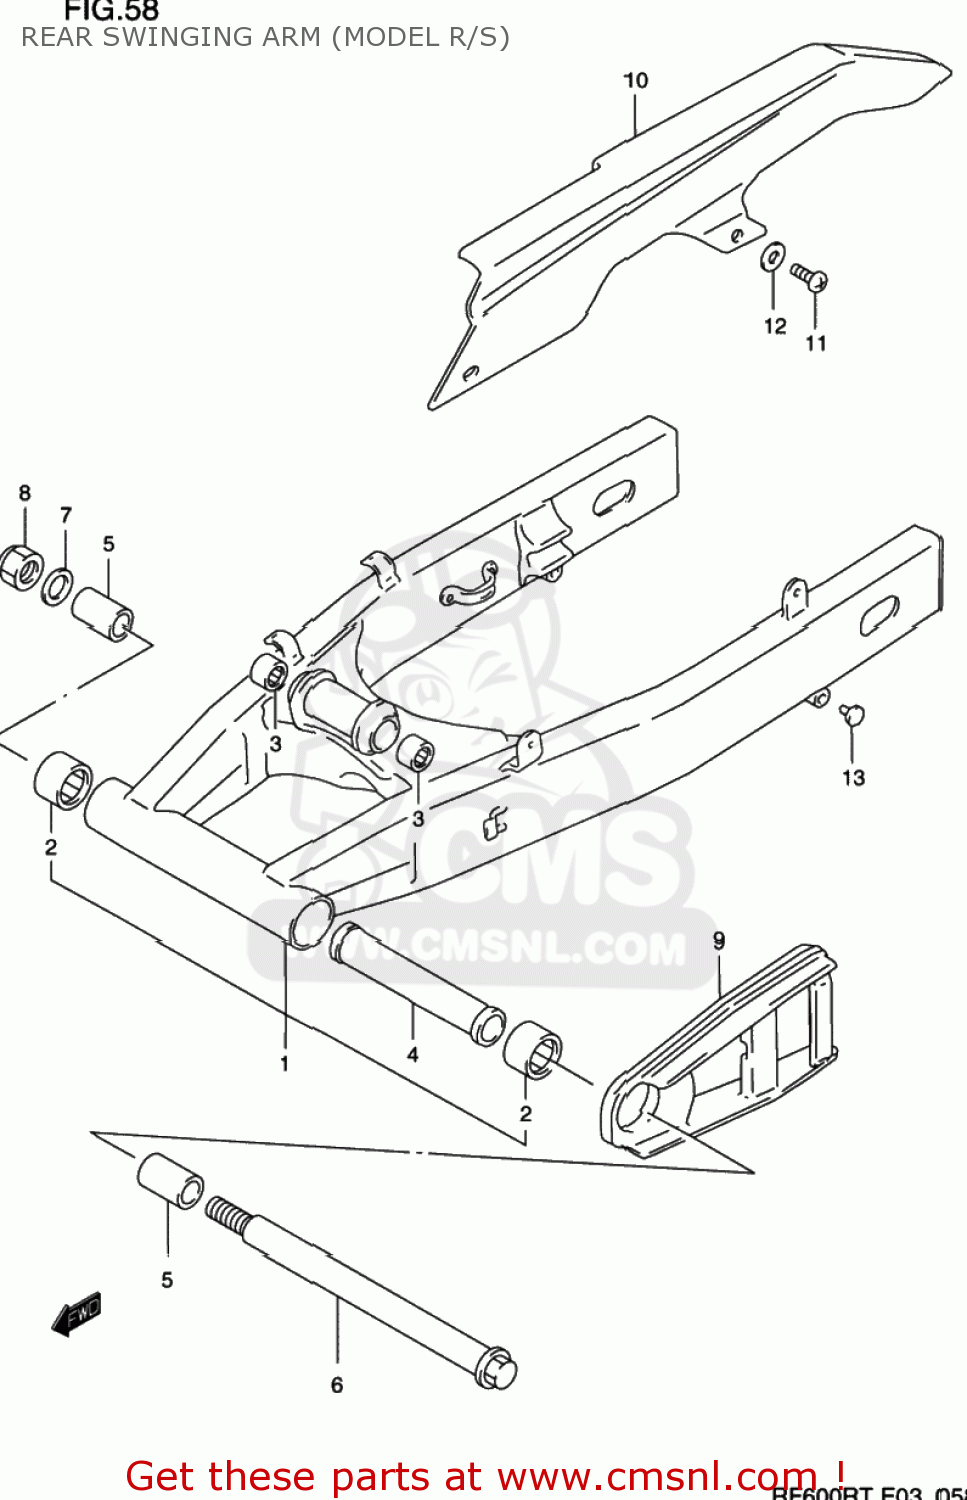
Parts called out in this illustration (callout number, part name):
1	SWING ARM ASSEMBLY,REAR
2	BEARING(25X33X35)
3	BEARING(17X24X25)
4	SPACER,REAR SWING ARM PIVOT
5	SPACER,RR SWGARM PIVOT
6	SHAFT,REAR SWING ARM
7	WASHER (18.2X28X2.6)
8	NUT
9	BUFFER,CHAIN TOUCH DEFENSE
10	CASE,CHAIN
11	SCREW 6X12
12	WASHER
13	CAP(OD:12)
